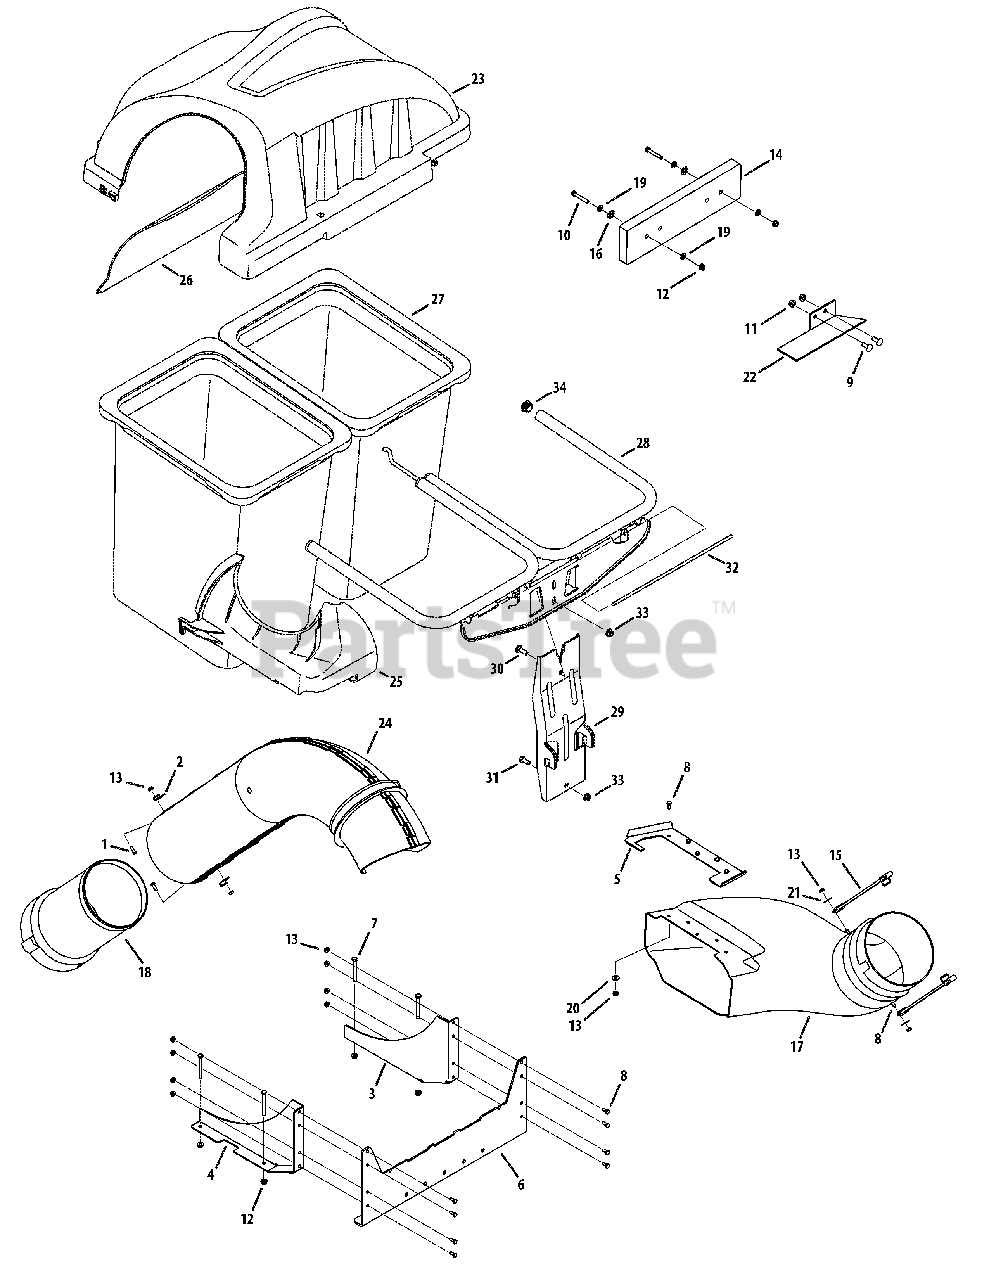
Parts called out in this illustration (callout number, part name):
1	Cap Screw, 1/4-20 x .750
2	Retainer Hook Bracket
3	Mount Assembly, RH
4	Mount Assembly, LH
5	Boot Mount Bracket
6	Catcher Mounting Bracket
7	Hex Head Screw, 5/16-18 x 2.75
8	Hex Head Screw, 1/4-20 x .620
9	Carriage Bolt, 3/8-16 x 1.00
10	Hex Head Screw, 5/16-18 x 2.00
11	Flange Lock Nut, 3/8-16
12	Flange Lock Nut, 5/16-18
13	Flange Lock Nut, 1/4-20
15	Chute Strap
16	Push Nut, 5/16
17	Discharge Chute Elbow
18	Chute Adapter
19	Flat Washer, .375 x .738 x .063
20	Belleville Washer
21	Flat Washer, .265 X 1.0 X .030
23	Twin Bagger Cover Assembly
24	Upper Chute Assembly
25	Upper Chute Support
26	Bagger Cover Screen
27	Grass-bag Assembly
28	Twin Bag Support Assembly
29	Vertical Support Bracket
30	Carriage Screw, 5/16-18 x 1.00"
31	Hex Head Screw, 5/16-18 x .75"
32	Cover Hinge Pin
33	Flange Lock Nut, 5/16-18
